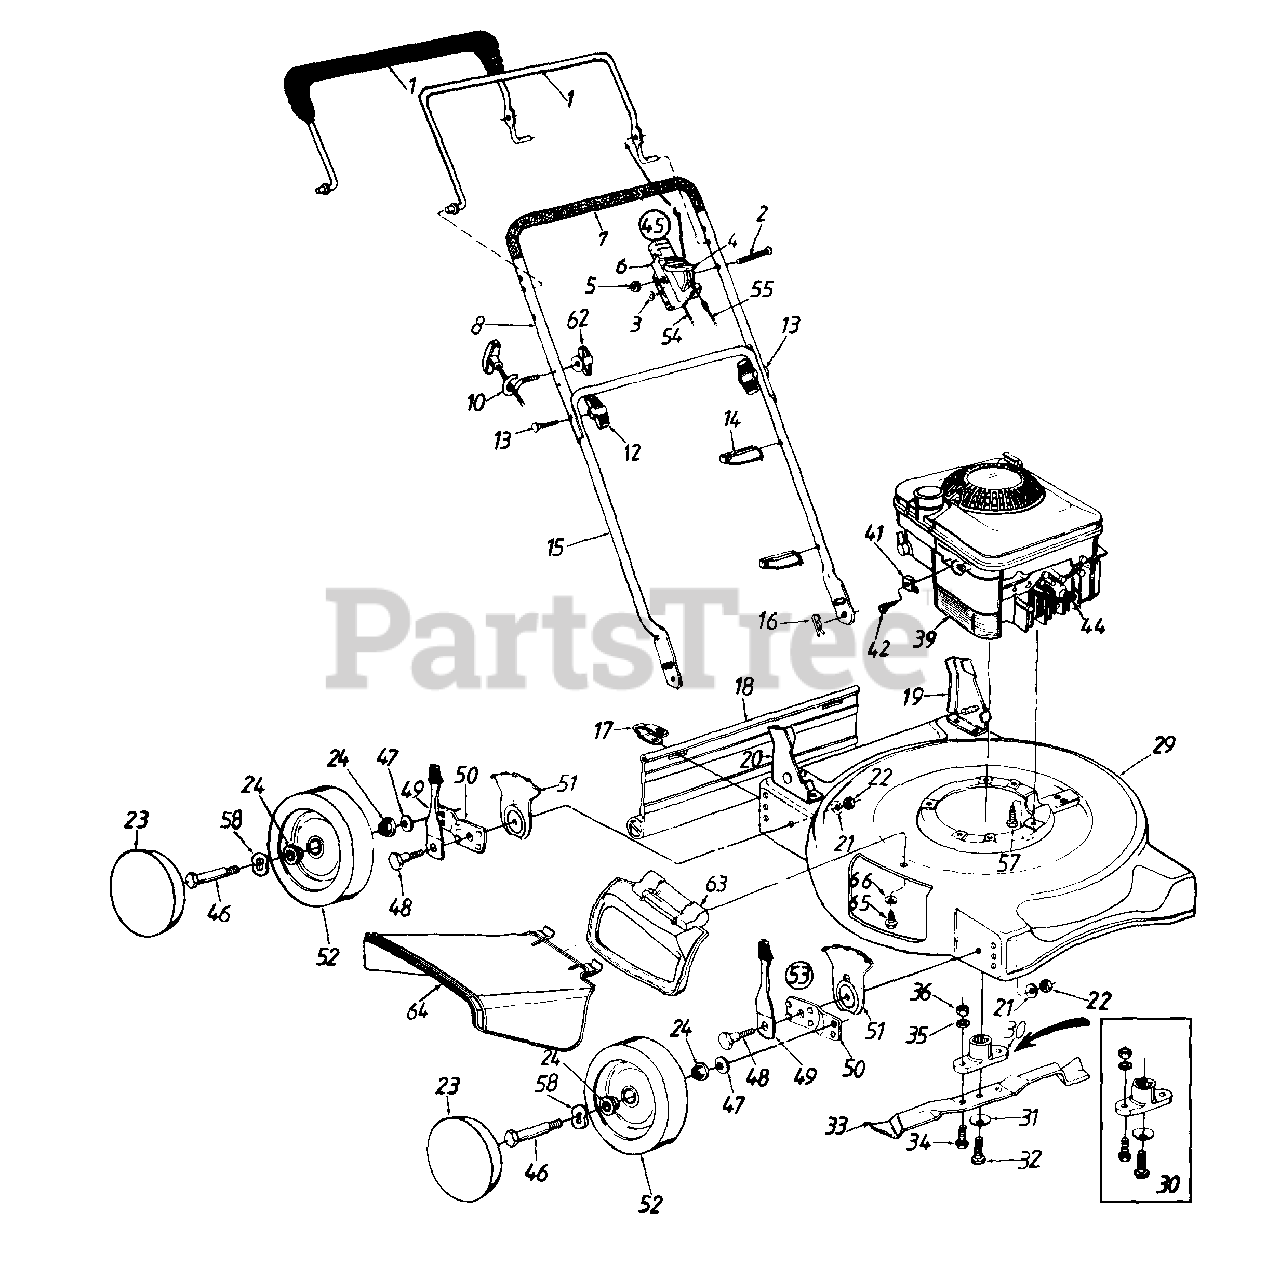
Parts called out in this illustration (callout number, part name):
1	Control Handle Ass'y.
2	Oval C-Sunk Scr.
3	Spr. Wash. .66" I.D.
4	Throttle Lever
5	Hex L-Nut 1/4-20 Thd.
6	Throttle Body
7	Grip
12	Hand Knob
13	Curved Hd. Bolt 5/16-18 x 2" Lg.
14	Cable Tie
16	Hairpin Cotter
17	Hinge Clip
18	Rear Flap
22	Hex Nut 3/8-16 Thd.
23	Hub Cap
24	Bearing
29	20" Deck Ass'y.
30	Blade Adapter Kit
31	Bell-Wash. .39" I.D.
32	Hex Bolt 3/8-24 x 1.5" Lg.
33	20" Mulching Blade
34	Hex Bolt 3/8-24 x 1" Lg.
35	L-Wash. 3/8" I.D.
36	Hex Nut 3/8-24 Thd.
39	Engine
41	Cable Clamp
42	Hex Self-Tap Scr. #10-32 x .62"
44	Spark Plug Boot
45	Throttle Box Comp.
46	Axle Bolt
47	Bell-Wash. .400" I.D. x .88"
48	Shld. Bolt .50" Dia. x .357"
49	Spring Lever Ass'y. w/Knob
51	Height Adj. Plate
52	Wheel Ass'y. Comp.
53	Height Adj. Ass'y. Comp. - R.F. & L.R.
54	Throttle Cable - 51"
55	Control Cable - 39"
57	Hex L-Wash. Hd. Scr. 3/8-16 x 1.0" Lg.
58	Wave Washer .51" I.D. (Used w/Ball Bearings)
62	Handle Knob 1/4-20 Thd.
63	Mulching Plug
64	Chute Deflector
65	Bell-Wash. 1/4" I.D.
66	Hex Wash. Hd. TT-Tap Scr. 1/4-20 x .5" Lg.
